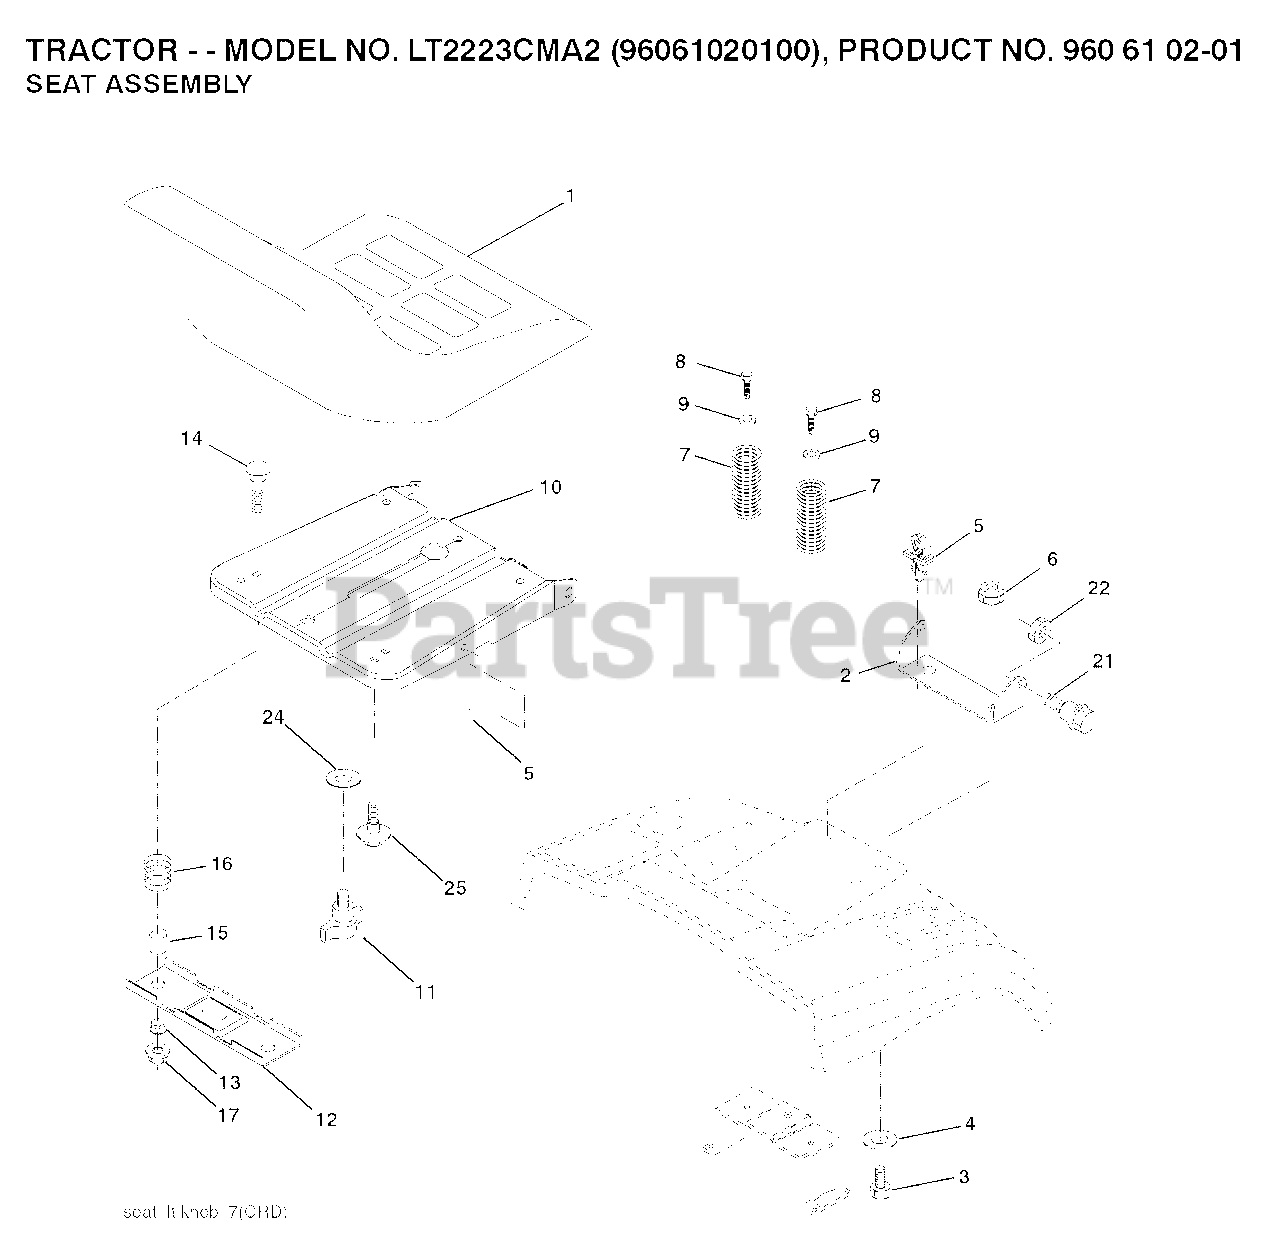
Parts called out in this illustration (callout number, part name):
1	SEAT.XG150.BLK.KB/SLD.NO-LOGO
2	SEAT PIVOT BRKT
4	WASHER PM
5	PUSH CLIP
6	NUT
7	SPRING COMPRESSION
8	SCREW 3/8-16X1
9	WASHER
10	PAN.ASM.SEAT.1SLOT
11	KNOB.SEAT.ADJ.WINGNUT
12	BRKT.MNTNG.SWITCH.SEAT
14	BOLT.ROUND.HEAD.SQUARE.NECK
15	SPACER SPLIT
16	SPRING COMPRESSED
17	NUT T
21	BOLT.SHOULDER.5/16-18
22	NUT.71038.31-18.HEX.NYLOCK
25	BOLT,SHOULD
